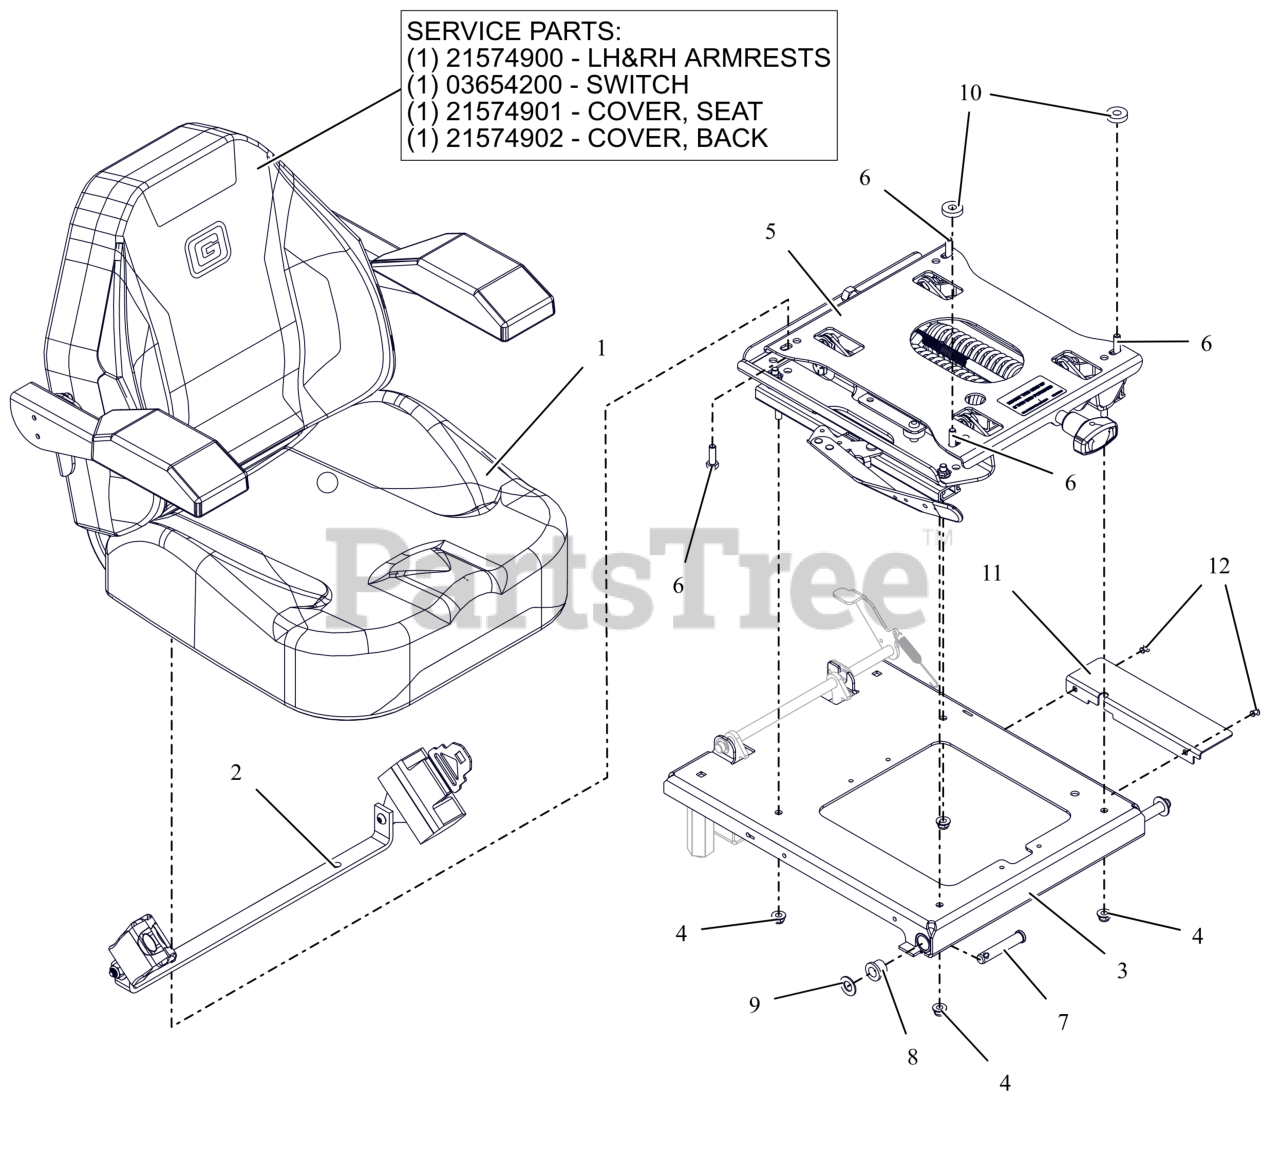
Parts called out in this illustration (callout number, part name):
1	SEAT, HD
1	LH&RH ARMRESTS
1	SWITCH- SEAT
1	COVER, SEAT - HD
1	SEAT COVER, BACK HD
2	KIT-SEAT BELT REPLACE-05007300
3	WLDMT, SEAT PLATE (BLACK)
4	NUT,NYL-FLG .31-18 GF ZCC
5	SUSPENSION, ULTRA LOW W/ SLIDES
6	BLT,HEX .31-18X1.00 G5 ZCC
7	PIN, SLIC-.500X42.70X2.31 -ZC
8	BSHG, FLG .516X.750X.625X.937
9	WSHR, FLT .531X1.00X.063 ZCC
10	WSHR, FLT .390X1.00X.250 ZCC
11	GUARD, SEAT PLATE (BLACK)
12	RIVET, .1875 AL/AL .126-.250
